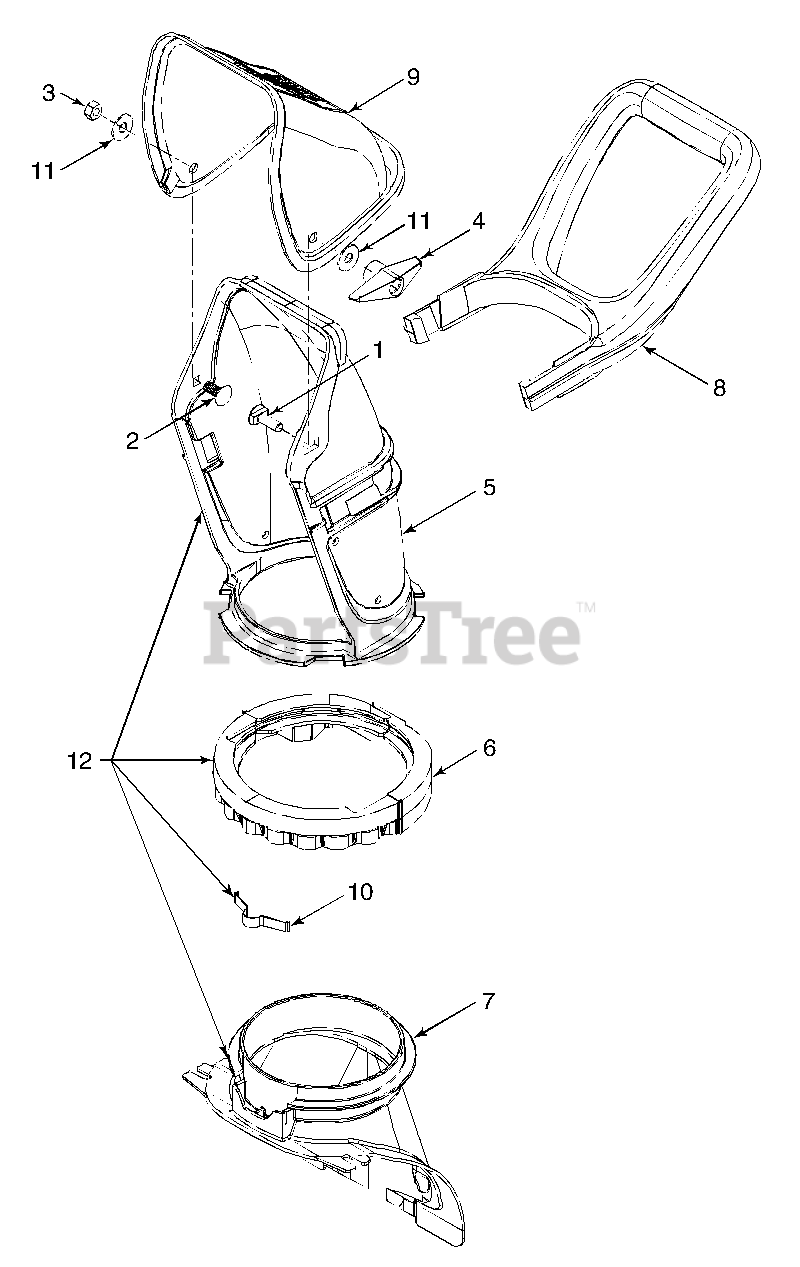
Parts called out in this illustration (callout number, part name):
1	Carriage Screw 5/16-18 x 1.0
2	Carriage Bolt 5/16-18 x .75
3	Hex Patch l-Nut 5/16-18
4	Handle Knob Assembly
5	Lower Chute 5" Dia
6	Ring-Lower Chute
7	Chute Adapter, 5" Dia.
8	Handle-Chute 5" Dia.
9	Upper Chute w/Export Label
10	Chute Adjustment Spring
11	Flat Washer .349 ID x .879 OD x .063
12	Lower Chute Ass'y
